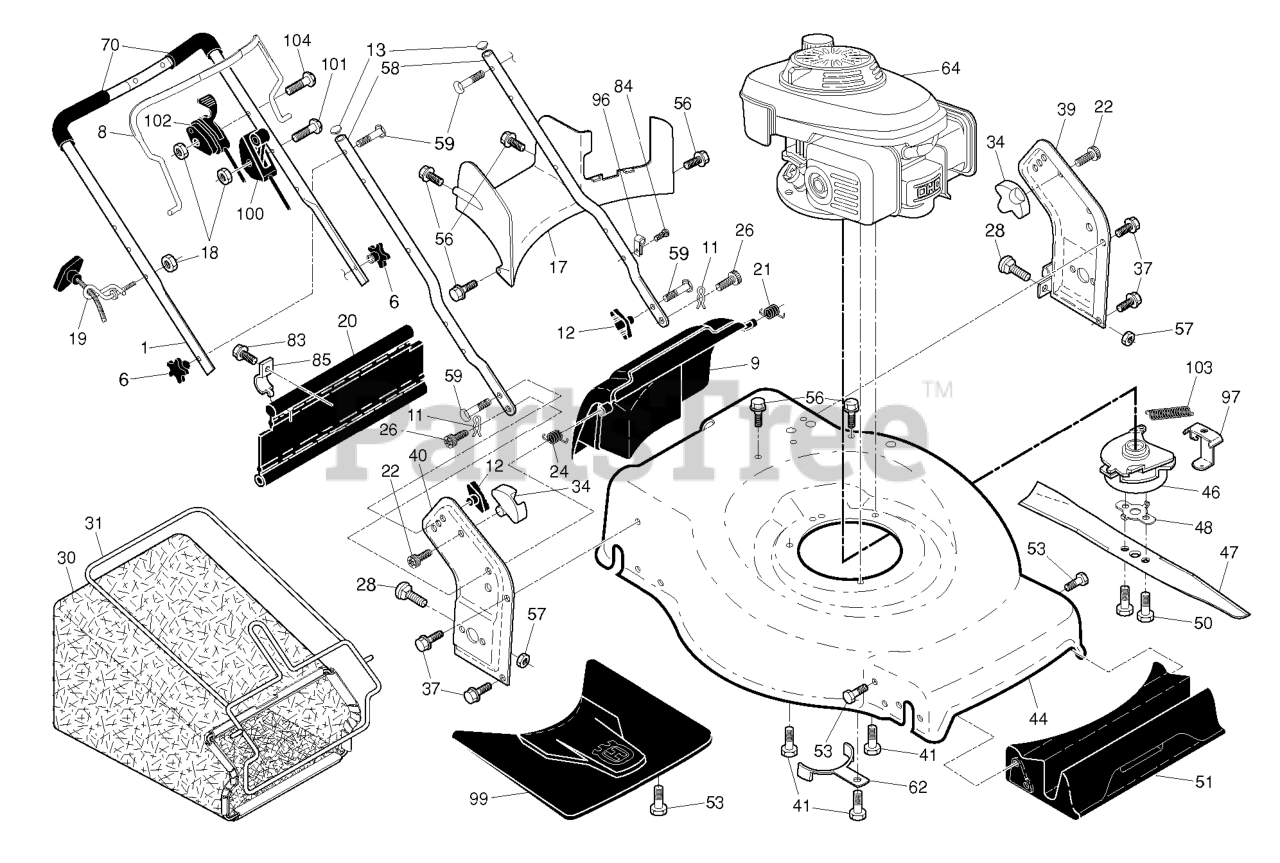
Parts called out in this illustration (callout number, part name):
1	HANDLE.ASM.UPPER.W/GRIP
6	KNOB.HANDLE.PLASTIC.STAR.BLACK
8	BAIL.CONTROL.HV.BBC.ORANGE
9	DOOR.REAR.ASM.22+.HUSQ.FG/RGD
11	COTTER.HAIRPIN.DOOR/HANDLE.PIV
12	KNOB, DEFLECTOR
13	PLUG.PLASTIC.7/8".14-20.GAUGE
17	RP.BAFFLE.REAR.22+.RGD.PL
18	NUT
19	RB GUIDE.ROPE.STD.BLK.ZIN WSL
20	SKIRT.REAR.22PLUS.RGD/FGD.NEW
21	SPRING.LH.BLACK
22	SCREW.PAN.HEAD.#10
24	SPRING.RH.GRAY
26	SCREW,DOOR/HANDLE.PIVOT
28	BOLT
30	GBAG.A3610247T.SILV.HUSWT.BLUE
31	RB FRAME.GBAG.22PLUS
34	BRACKET.GRASSBAG.ATTACHING.BLK
37	BOLT.5/16HEX.WHS.HD
39	BRACKET.ASM.HANDLE.LT
40	RP.BRACKET.ASM.HANDLE.RT.22+.
41	BOLT 3/8-16X1-1/8
44	HOUSING.22+.RWD.HD.WO/PORT.ORA
46	Husqvarna TBD
47	BLADE.FUSION.HONDA.BBC.HUSQ.
48	SPACER.BLADE.HONDA.BBC
50	BOLT.BLADE
51	BAFFLE.FRONT.22PLUS.PLASTIC RP
53	SCREW.HI-LO.5/16 X.75
56	SCREW.HX.13X.750
57	NUT.FLANGE.5/16
58	HANDLE.LOWER.22+BT.2PC.GRY
59	BOLT, HANDLE 5/16-18X1.75
62	BRACKET.KEEPER.BELT
70	GRIP.HANDLE.FOAM.WIDE.(1 SIDE)
83	TAPPING SCREW
84	FASTENER.PUSH.O.250X0.783
85	BRACKET.SKIRT.22+.BZP
96	CLIP.CABLE.BLK
97	BRACKET.BBC.MOUNTING
99	COVER.ASM.FRONT.SHROUD.HUSQ.
100	CONTROL.THROTTLE.HOND.BBC.58.5
102	CONTROL.HONDA.GREY/BLACK
103	SPRING.BBC
